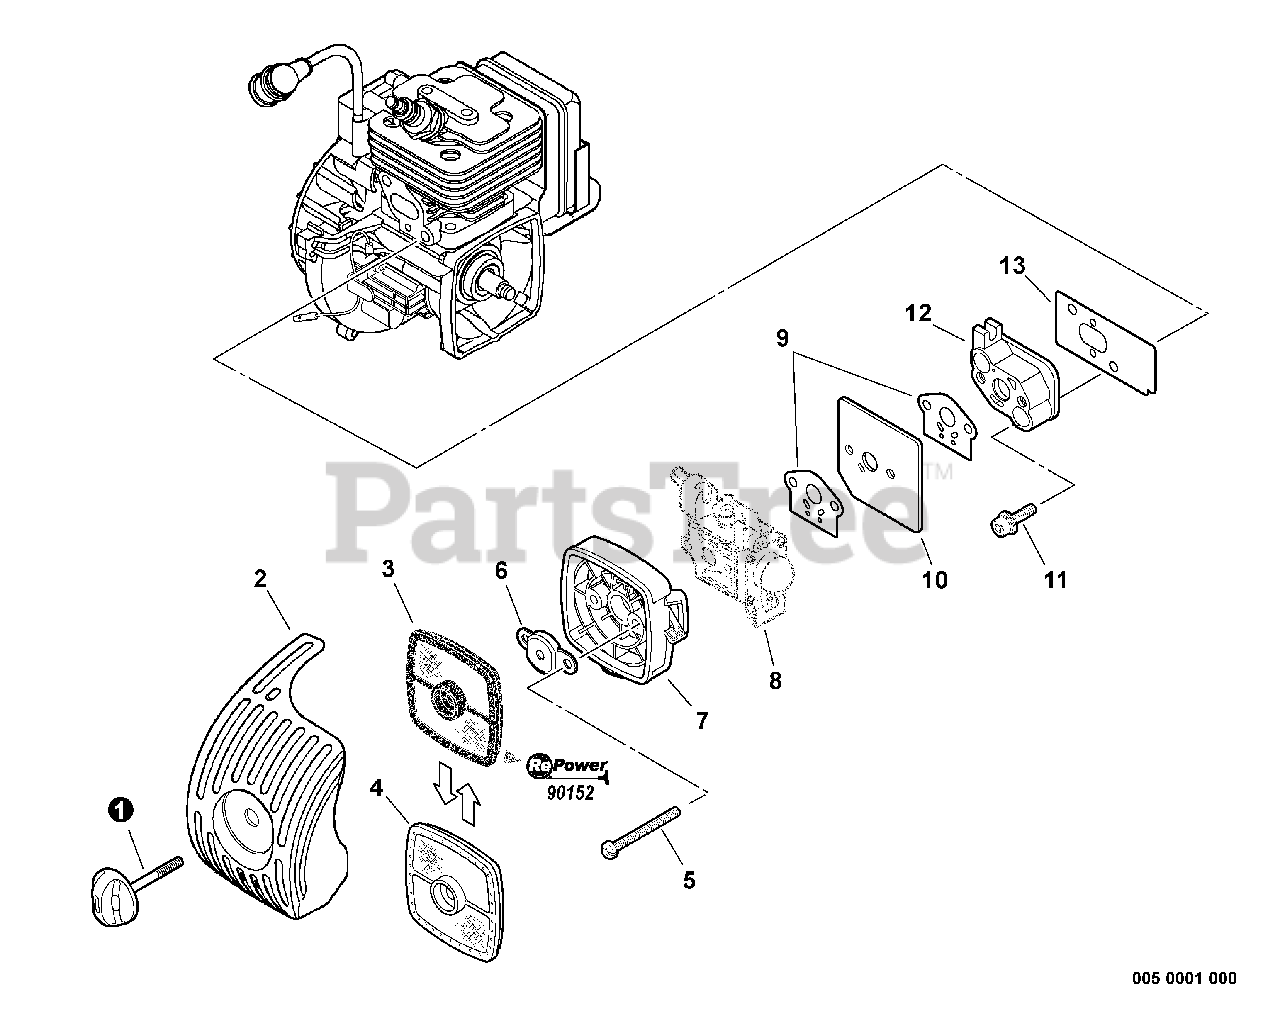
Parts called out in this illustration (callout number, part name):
1	THUMBSCREW
2	COVER, AIR FILTER
3	FILTER, AIR - DOUBLE LAYER
4	FILTER, AIR - SINGLE LAYER
5	SCREW - 5X65
6	PLATE, PREVENT
7	CASE, AIR FILTER - BLACK
8	CARBURETOR
9	GASKET, INTAKE
10	PLATE, INSULATOR
11	SCREW - 5X25
12	INSULATOR, INTAKE
13	SHIELD, INTAKE
14	RePower TUNE-UP KIT
